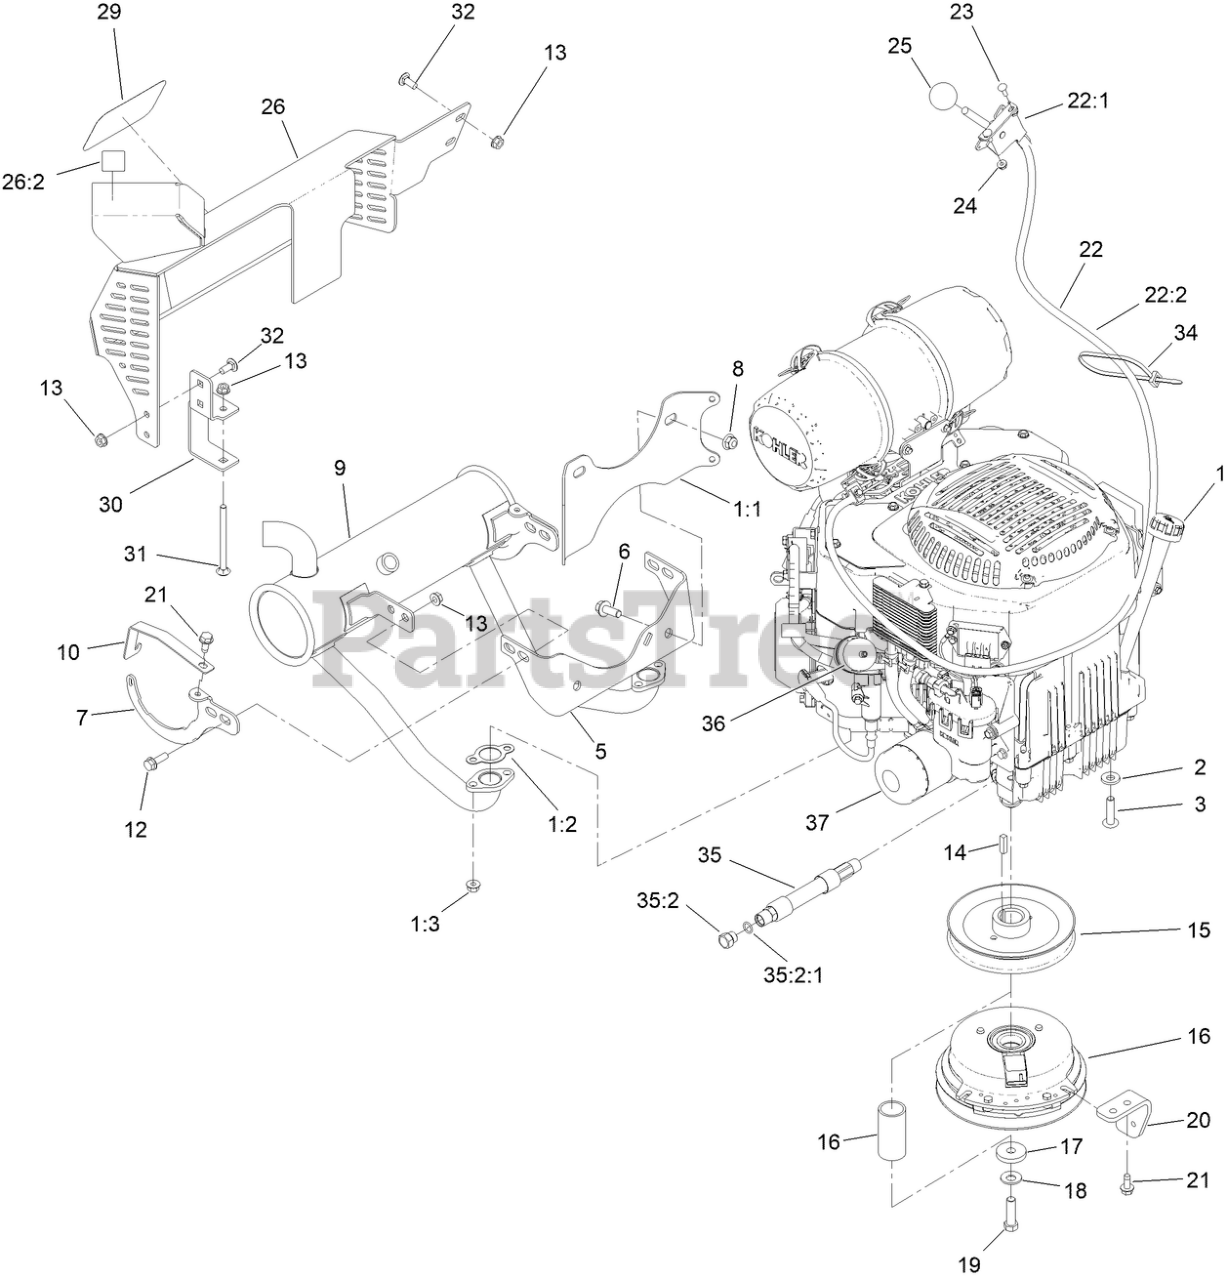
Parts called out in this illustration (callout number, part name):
1:1	BRACKET-MUFFLER
1:2	GASKET-EXHAUST
1:3	NUT-FLANGE
2	WASHER-BELLEVILLE
3	SCREW-BHTF
5	BRACKET-MUFFLER
6	SCREW-HHF
7	SUPPORT-MUFFLER
8	NUT-HF, NI
9	MUFFLER-KOHLER
10	BRACKET-MUFFLER, KOH
12	SCREW-HHF
13	NUT-HF
15	PULLEY
16	CLUTCH-200CMS
17	WASHER
18	WASHER-SPRING
19	SCREW-HH
20	STOP-CLUTCH
21	SCREW-HWHTF
22	THROTTLE ASM
22:1	LEVER-CONTROL
22:2	CABLE-THROTTLE
23	BOLT-CARR
24	NUT-LOCK, FLANGE
25	KNOB-BALL
26	MUFFLER GUARD ASM
26:2	DECAL-WARNING
29	DECAL
30	BRACKET-MOUNTING, GUARD
31	SCREW-CARR
32	SCREW-CARR
34	TIE-CABLE
35	HOSE ASM
35:2	PLUG-HH
35:2:1	O-RING
36	FILTER-FUEL
37	FILTER-OIL
